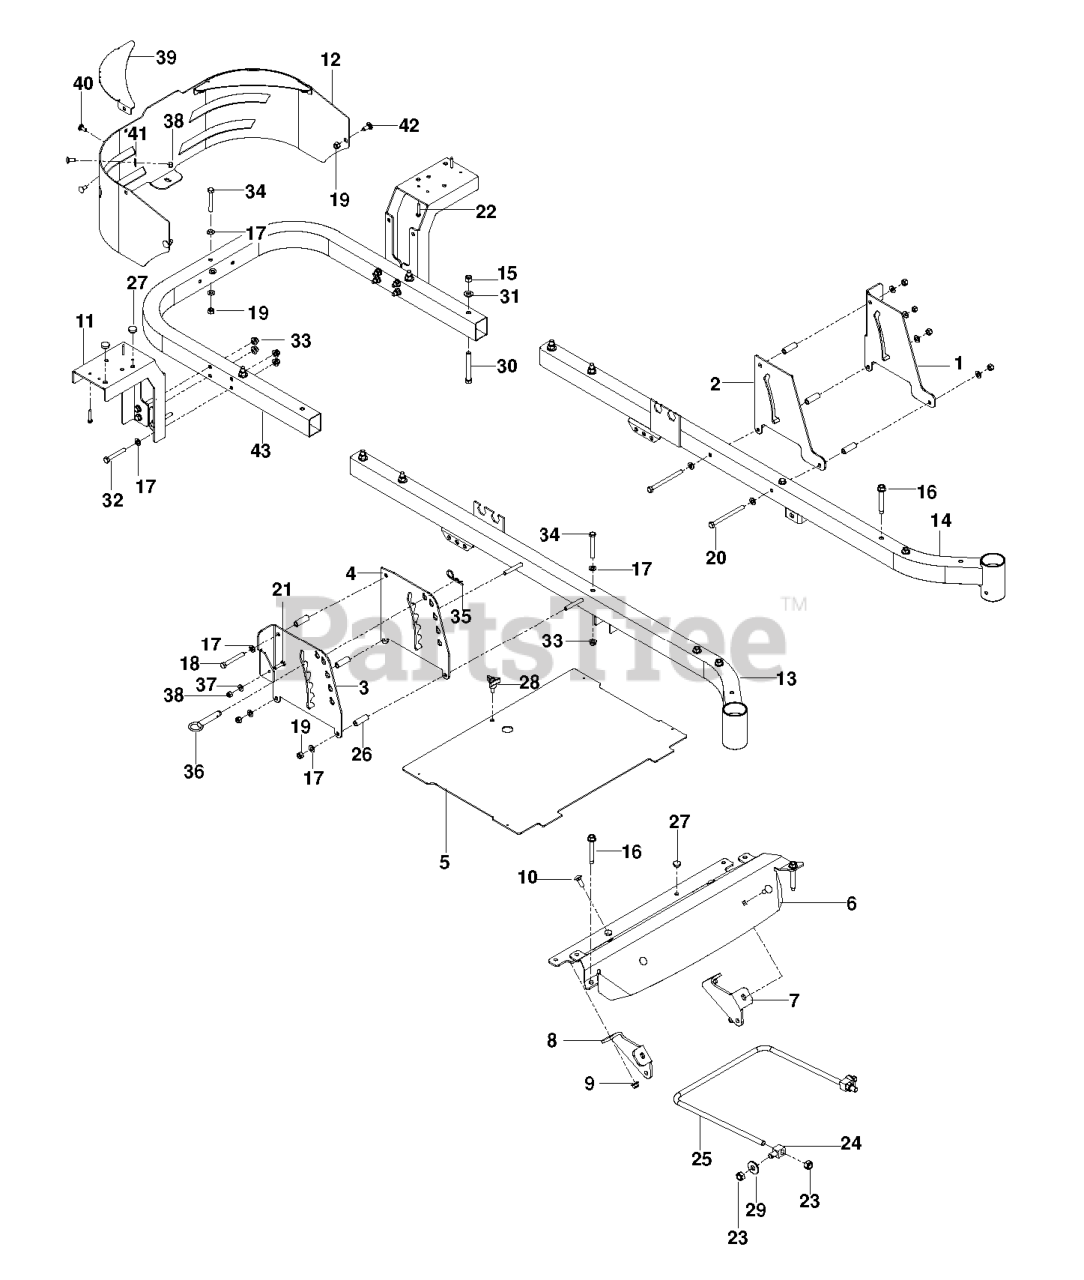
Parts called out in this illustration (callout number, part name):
1	PLATE, OUTER BRAKE, BLACK
2	PLATE, BRAKE LATCH, BLACK
3	PLATE, DECK HEIGHT, BLK EZ
4	PLATE, DECK HEIGHT, BLACK
5	PLATE, FOOT W/DECALS EZ
6	FOOT REST WIDE ORG
7	MOUNT, STRUT, RT, BLK
8	MOUNT, STRUT, LT, BLK
9	NUT 3/8-16 HEX FLG NYLOC ZD
10	RHSNB 3/8C X 1
11	SUPPORT, FENDER, BLACK
12	GUARD, REAR, ORANGE
13	FRAME, RT, ORANGE
14	FRAME, LT, ORANGE
15	NUT 3/8-16 NYLOC
16	ENGINE BOLT, SPECIAL
17	FLAT WASHER 5/16 SAE
18	BOLT 5/16C X 2 1/2
19	NUT 5/16 NYLOC
20	HCS 5/16C X 4
21	HCS 1/4C X 1
22	SCR #10-12X1-1/2HEX WASH HD ZD
23	7/16-14 HEX NUT W/NYL RING ZD
25	LINK, FRONT SUSP.
26	SPACER, .334 ID X .5 OD X 1.5
27	GROMMET, BUMPER
28	KNOB W/STUD
29	WASH USS FLAT 1/2
30	HCS 3/8C X 3
31	WASHER 3/8 SAE FLAT
33	5/16-18 NYLOC FLANGE NUT
34	HCS 5/16C X 2-3/4
35	HAIRPIN #4
37	WASHER 1/4 SAE
38	NUT.1/4-20.HEX.NYLOC.ZD
39	SUPPORT, CORNER, ORANGE
40	RHSSNB, 1/4-20X5/8
41	WASHER 1/4 FLAT
42	BOLT 5/16C X 3/4" CARRIAGE
43	FRAME TUBE, REAR, ORANGE
